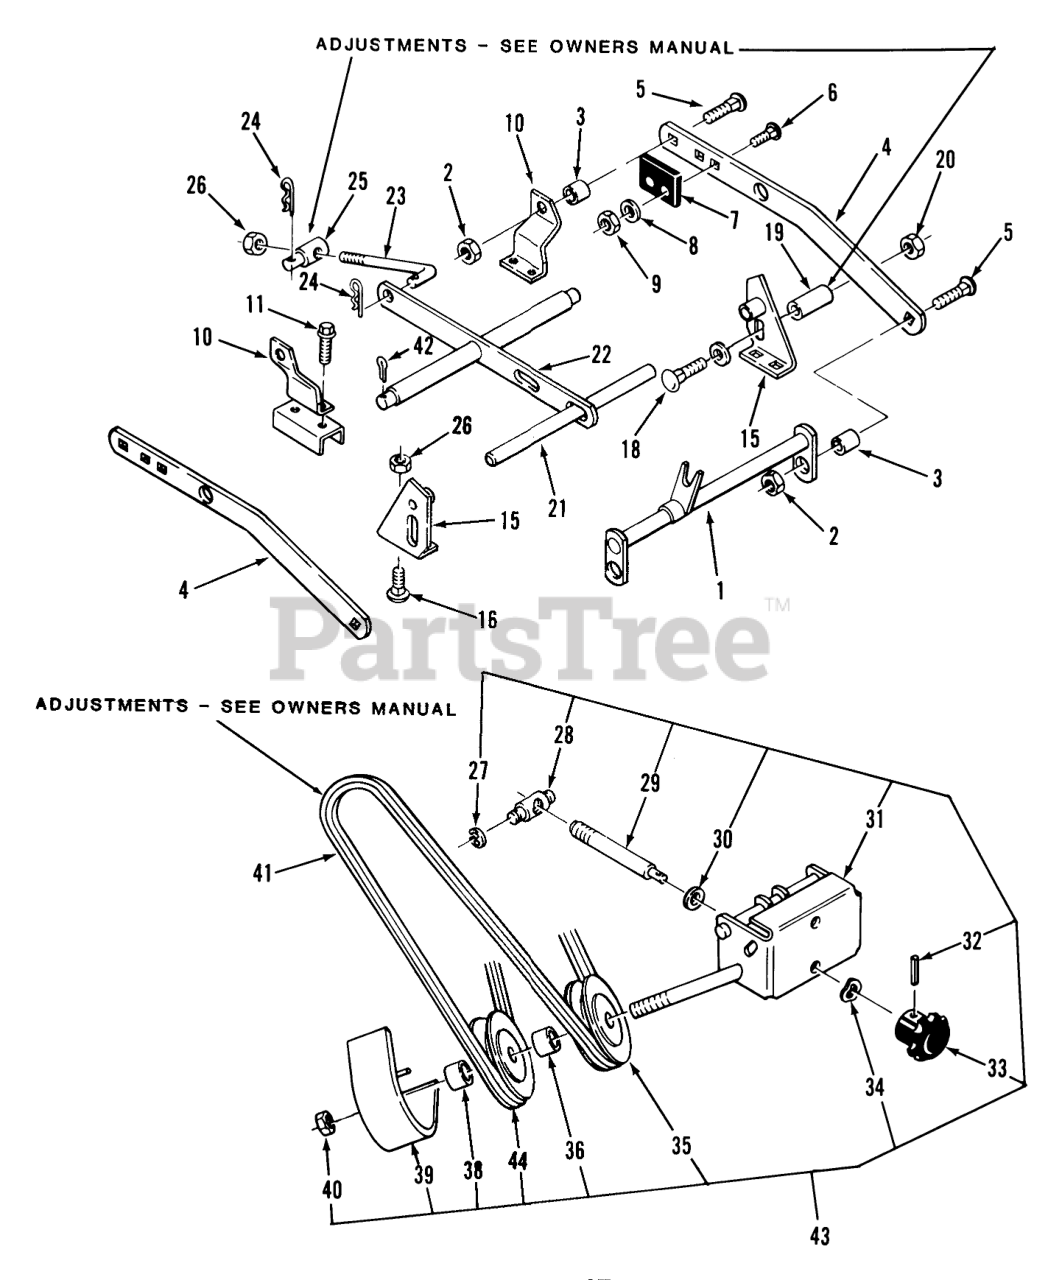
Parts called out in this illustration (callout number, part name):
1	Hitch
2	LOCKNUT-FLANGE
3	SPACER
4	Bar Draft
5	Bolt
6	Bolt-Carriage
7	BUMPER
8	Collar
9	Nut
10	Bracket-Rear Deck
11	Bolt
15	BRKT-FRNT DCKR
16	Bolt
18	CARRIAGE BOLT -4
20	Nut
21	Front Shaft
22	Leveler
23	Lift Rod
24	Hairpin
25	TRUNNION-LIFT
26	NUT
27	RING-RETAINING
28	TRUNNION-DOUBLE
29	ROD ADJ
30	Washer
31	Front Support
32	PIN-ROLL
33	KNOB-ADJUSTMENT
34	WASHER-SPRING
35	Pulley-V
36	SPACER
38	SPACER-OUTER
39	Belt Cover
40	Nut
41	Drive Belt 05-37SC02
41	Drive Belt 05-37SC01
42	Cotter Pin
43	ASM-SUPPORT,IDLER
44	PULLEY-FLAT IDLER
44	Pulley-V
